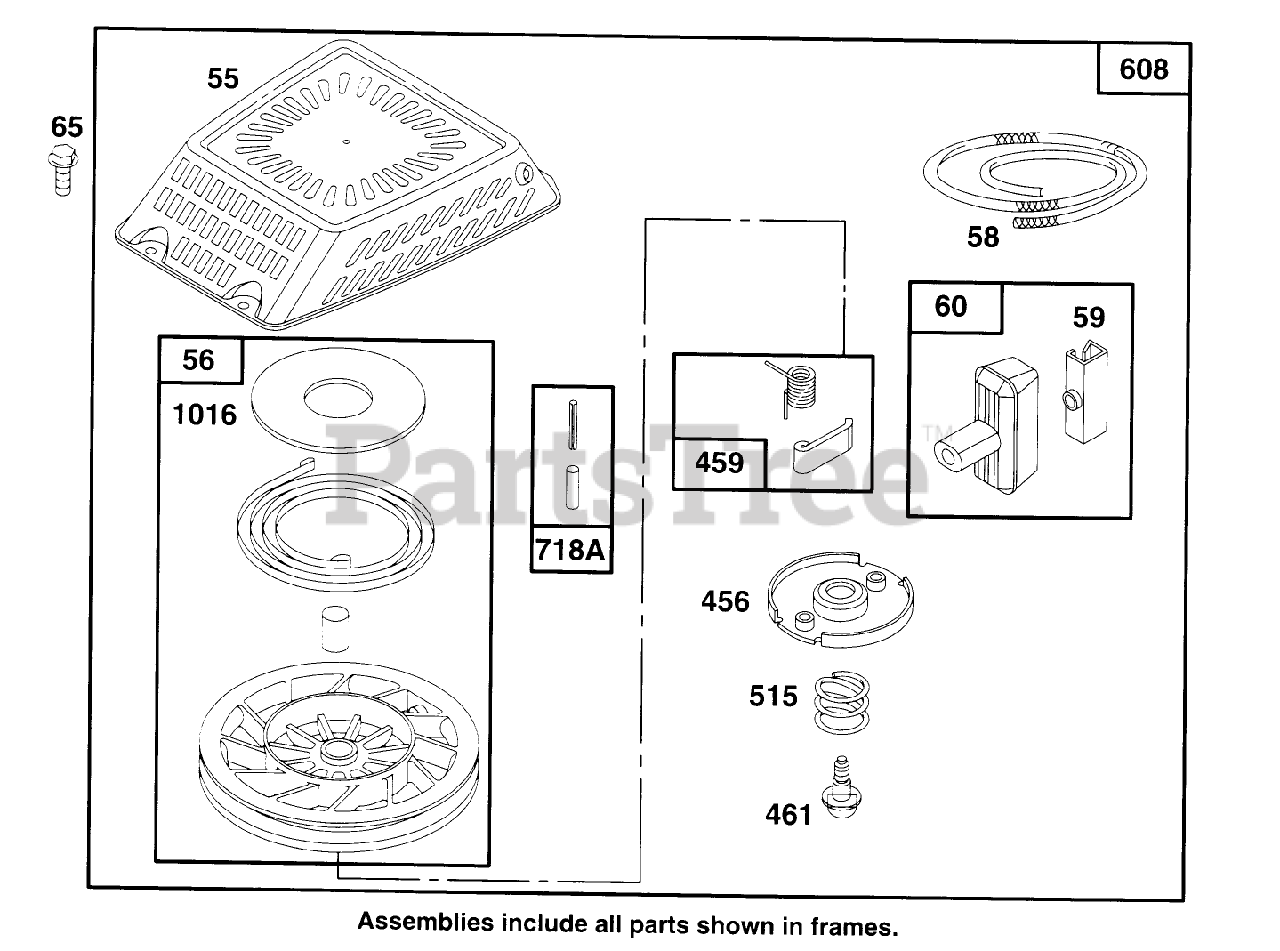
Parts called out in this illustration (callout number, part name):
55	Housing-Rewind Starter
59	INSERT-HANDLE, REWIND
456	RETAINER - SPRING
515	SPRING - RETAINER
